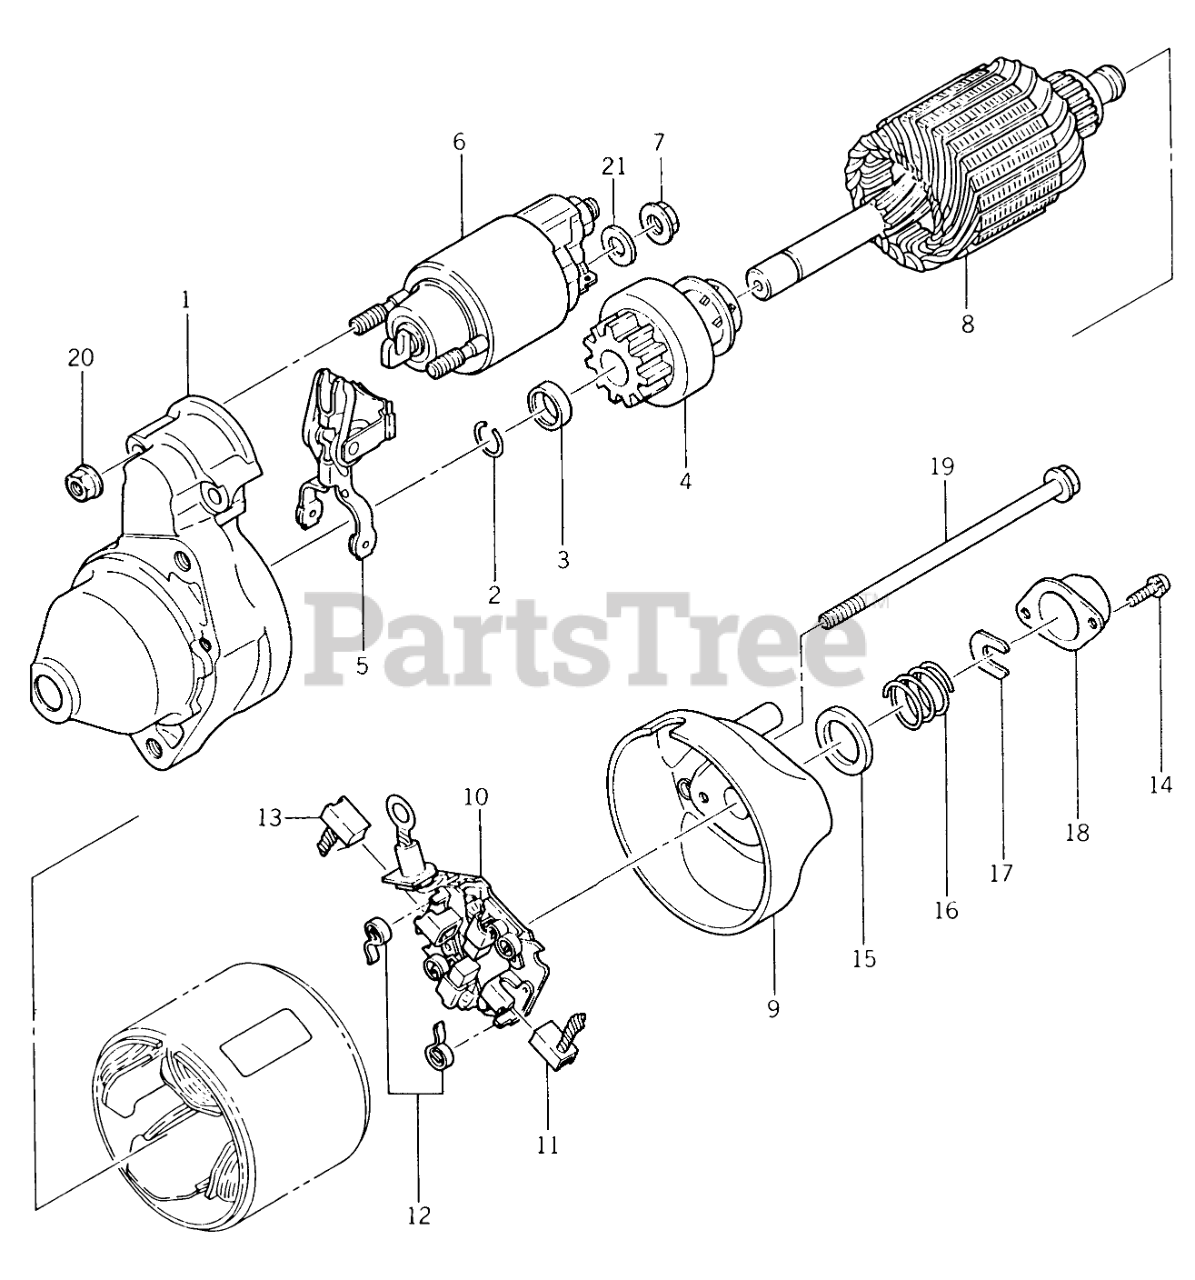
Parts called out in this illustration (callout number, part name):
1	COVER ASS'Y
2	RING-SNAP
3	STOPPER PINION
4	CLUTCH ASS'Y
5	LEVER SHIFT
6	SWITCH ASS'Y
8	ARMATURE
9	COVER ASS'Y
10	BRUSH HOLDER ASS'Y
11	BRUSH
12	Spring
13	BRUSH
14	SCREW
16	SPRING
17	STOPPER
18	COVER
21	Washer
